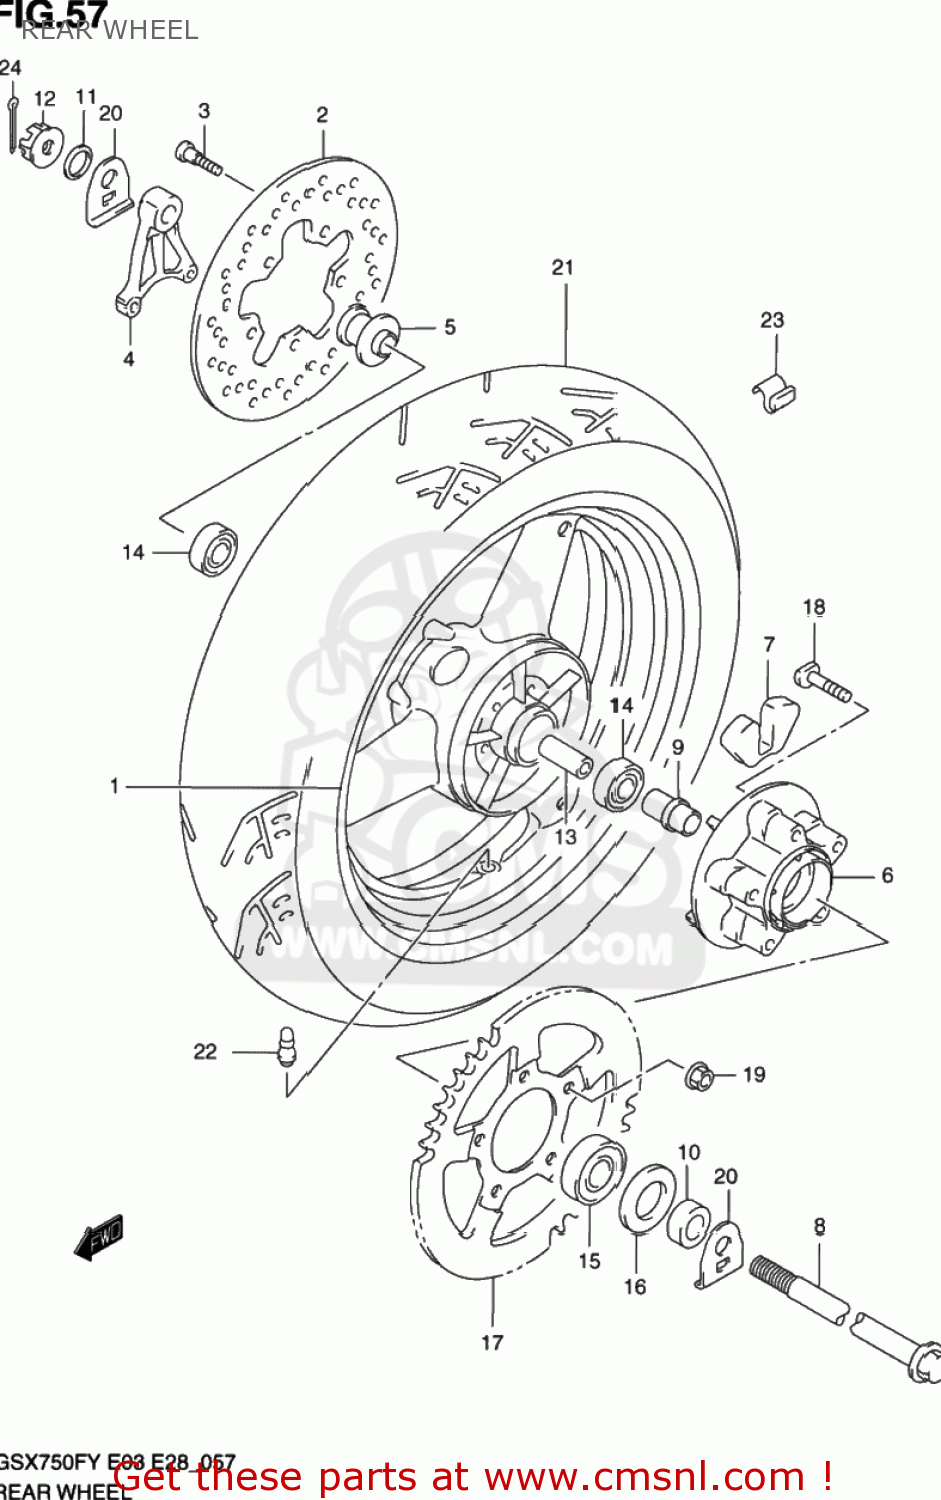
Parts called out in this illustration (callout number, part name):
1	WHEEL,REAR (17XMT4.50)
2	DISC,RR BRAKE
3	BOLT 8X33
4	BRACKET,RR CALIPER
5	SPACER,RR AXLE,R
6	DRUM,RR SPROCKET
7	ABSORBER,RR HUB SHOCK
8	AXLE,RR
9	RETAINER,RR SPROCKET DRUM
10	SPACER,RR AXLE,R
11	WASHER(17X30X3.2)
12	NUT
13	SPACER(17.5X25X88)
14	BEARING
15	BEARING(25X62X17)
16	SEAL,OIL(35X62X8)
17	SPROCKET,RR(NT:45-530)
18	BOLT(10X47)
19	NUT
20	WASHER,CHAIN ADJUSTER
21	TIRE,RR(150/70 ZR17 69W)
22	VALVE ASSEMBLY,WHEEL,TR412
23	BALANCER,WHEEL (10G)
24	PIN,COTTER
